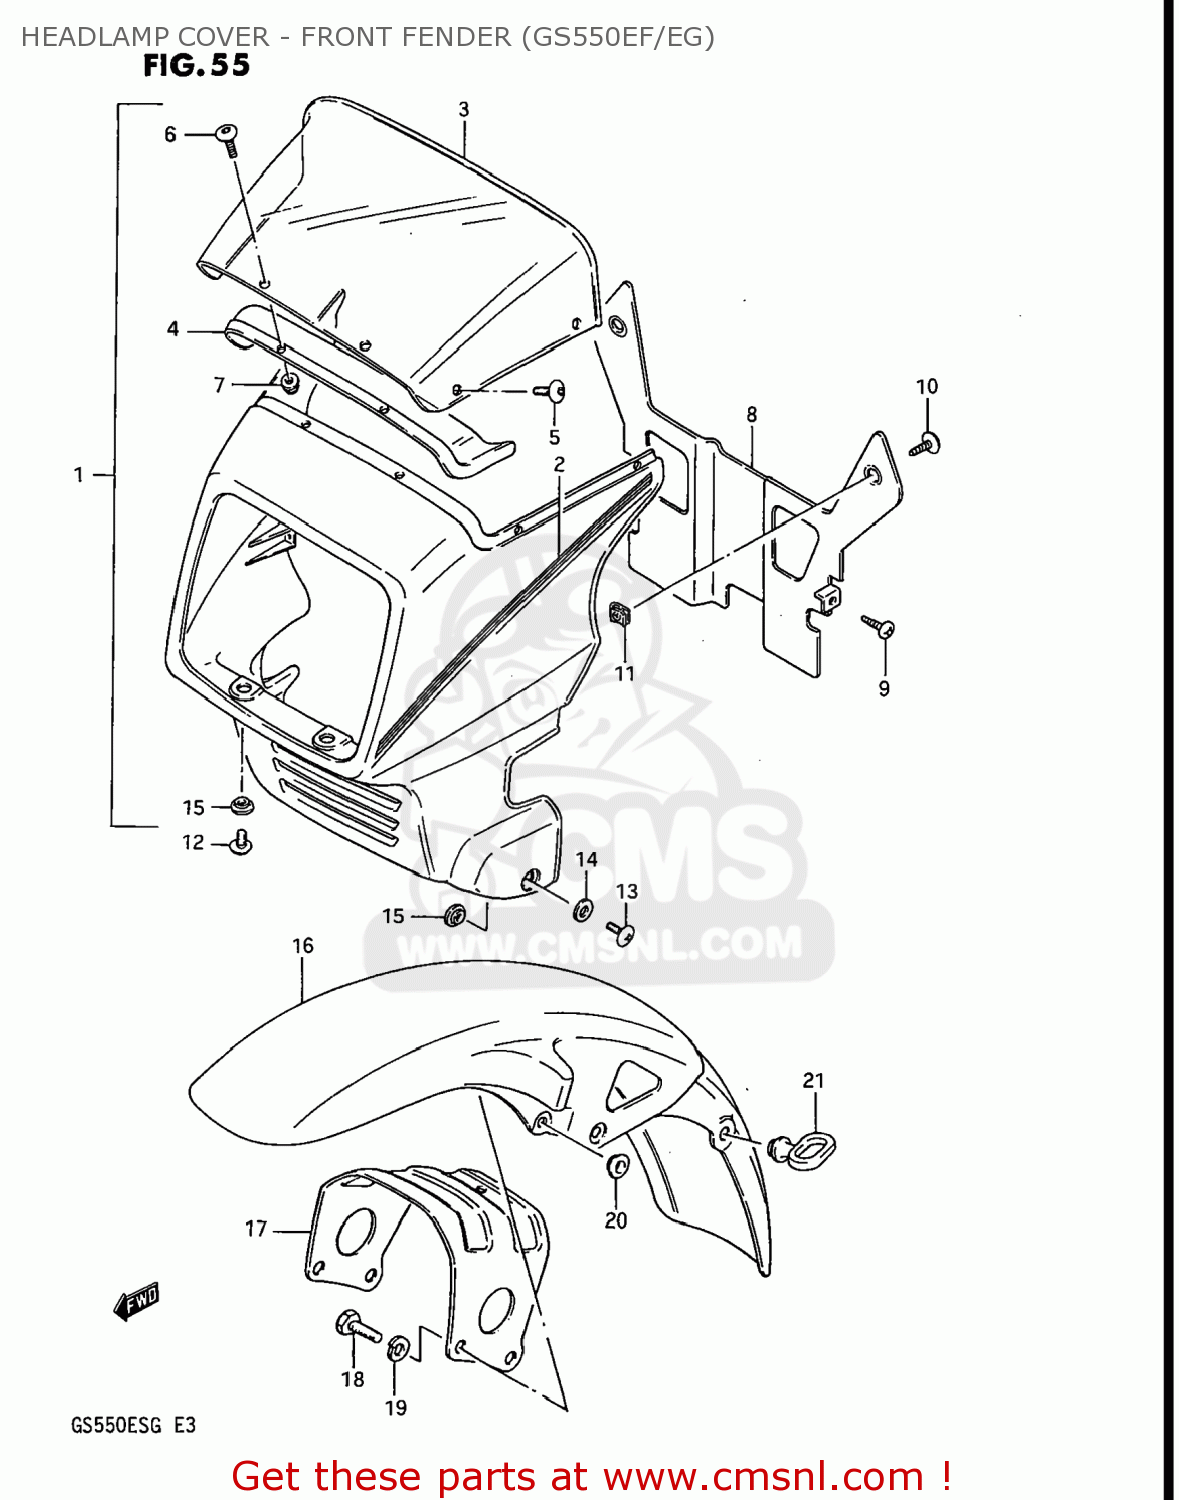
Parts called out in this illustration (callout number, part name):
1	HOUSING ASSEMBLY,HEADLAMP
2	TAPE SET,HEADLAMP
3	WINDOW,COVER HEADLAMP
4	COVER,HEADLAMP,UPPER
5	SCREW(5X12)
6	SCREW
7	NUT
8	PLATE,HEADLAMP COVER
9	SCREW
10	SCREW
11	NUT
12	SCREW 6X12
13	SCREW 6X12
14	WASHER (6.5X18X1.6)
15	WASHER
16	FENDER,FRONT
17	BRACE,FRONT FENDER
18	BOLT
19	LOCK WASHER
20	WASHER
21	GUIDE,CABLE
